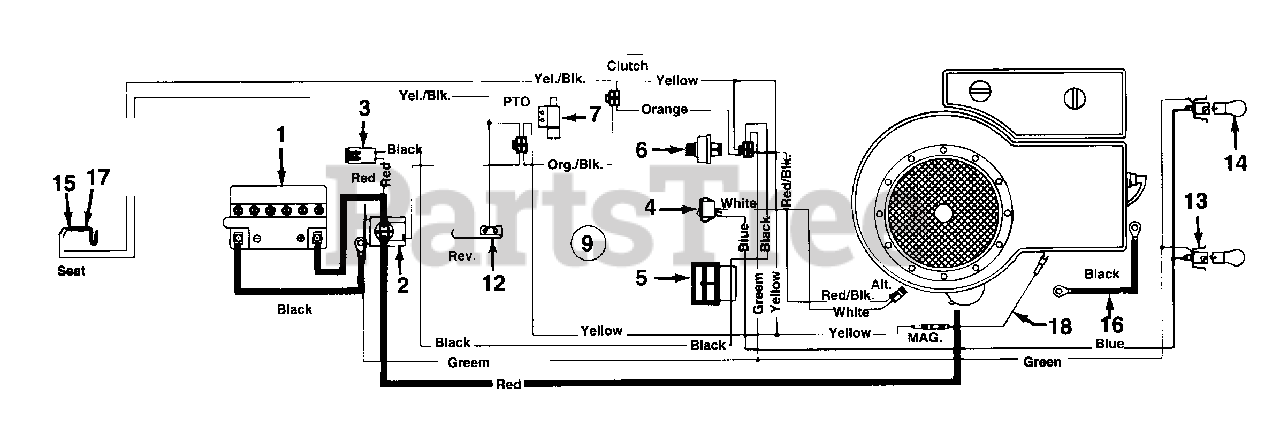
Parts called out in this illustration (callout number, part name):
1	Battery
2	Solenoid
3	Fuse 7.5 Amps
4	Light Switch
5	Ammeter
6	Ignition Switch
7	Safety Switch (Clutch)
9	Wire Harness w/o Ammeter
12	Safety Switch (Reverse)
13	Socket
14	Bulb (Headlight)
15	Safety Switch (Seat)
16	Ground Wire 7.5" Lg.
17	Safety Switch (Seat)
18	Harness Adaptor
